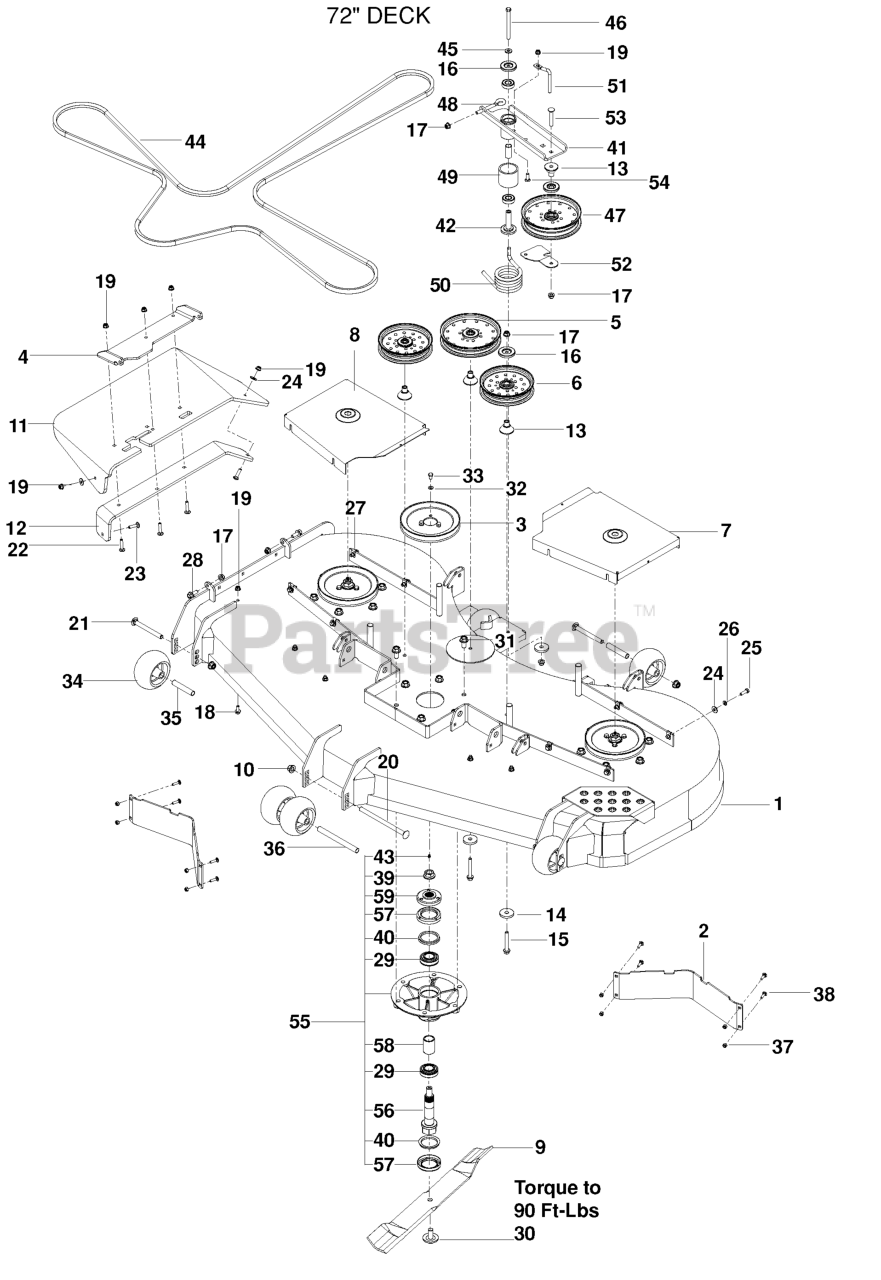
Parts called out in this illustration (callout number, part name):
1	DECK.SVC.W/DECALS.72.ORANGE.HU
2	BAFFLE, DIVERTER 72" BLACK
3	PULLEY - 7.50
4	BRKT - CHUTE MTG BLACK
5	PULLEY - 7" NARROW
6	PULLEY IDLER, 6" NARROW
7	SHIELD, BELT 72 R.H. ORANGE
8	SHIELD, BELT 72 LH ORANGE
9	BLADE OEM - 25"
10	NUT, 1/2-13 HEX FLG NYLOC ZD
11	CHUTE, DISCHARGE 60-72
12	BRKT - CHUTE SUPPORT BLACK
13	BEARING, IDLER ARM
14	SPINDLE WASHER
15	HHFS 3/8-16 X 2 3/4
16	DUST SHIELD
17	NUT 3/8-16 HEX FLG NYLOC ZD
18	HHFS 5/16-18 X 3/4
19	5/16-18 NYLOC FLANGE NUT
20	RHSNB 1/2-13 X 8 GR5 ZD
21	RHSNB 1/2-13 X 4.75 GR5 ZD
22	RHSNB 5/16-18 X 1-1/2 GR 5 ZD
23	BOLT, CARRIAGE 5/16X1-1/4
24	WASHER 5/16 FLAT
25	HCS 5/16C X 1
26	WASHER.LOCK.HVY.HLCL.SPR.5/16
27	U-CLIP 5/16-18 NUT RETAINER
28	HHFS 3/8-16 X 1 GRD 5 ZD
29	BEARING - 206KRR8
30	BLADE BOLT/WASHER
31	HHFS 1/2-13 X 1 GR5 ZD
32	WASH 5/16 DISC SPRING ZD
33	HCS 5/16-18 X 1/2 GR 5 ZD
34	ROLLER, GAUGE .635 BORN
35	TUBE, ROLLER AXLE
36	TUBE, ROLLER AXLE LONG
37	NUT.1/4-20.HEX.NYLOC.ZD
38	1/4-20X3/4 CARR BLT
39	NUT FLANGE 3/4-16
40	V-RING, 55MM
41	ASSY, IDLER ARM, PZ
42	BEARING, IDLER PIVOT
43	ZERK
44	BELT, "B", 201
45	WASHER, 3/8 THICK
46	HCS 3/8-16 X 4-1/2 GR 8 ZD
47	PULLEY - IDLER 7"
48	EYE BOLT, 3/8 X 4"
49	SPACER, IDLER PIVOT
50	SPRING, TORSION, IDLER
51	BELT KEEPER
52	BELT.GUIDE.BLACK
53	CARRIAGE BOLT 3/8-16 X
54	RHSSNB 5/16C X 1.0
55	SPINDLE ASM. 10"
56	SHAFT - SPINDLE
57	CUP - DEBRIS
58	SPACER - BEARING
59	HUB - PULLEY
